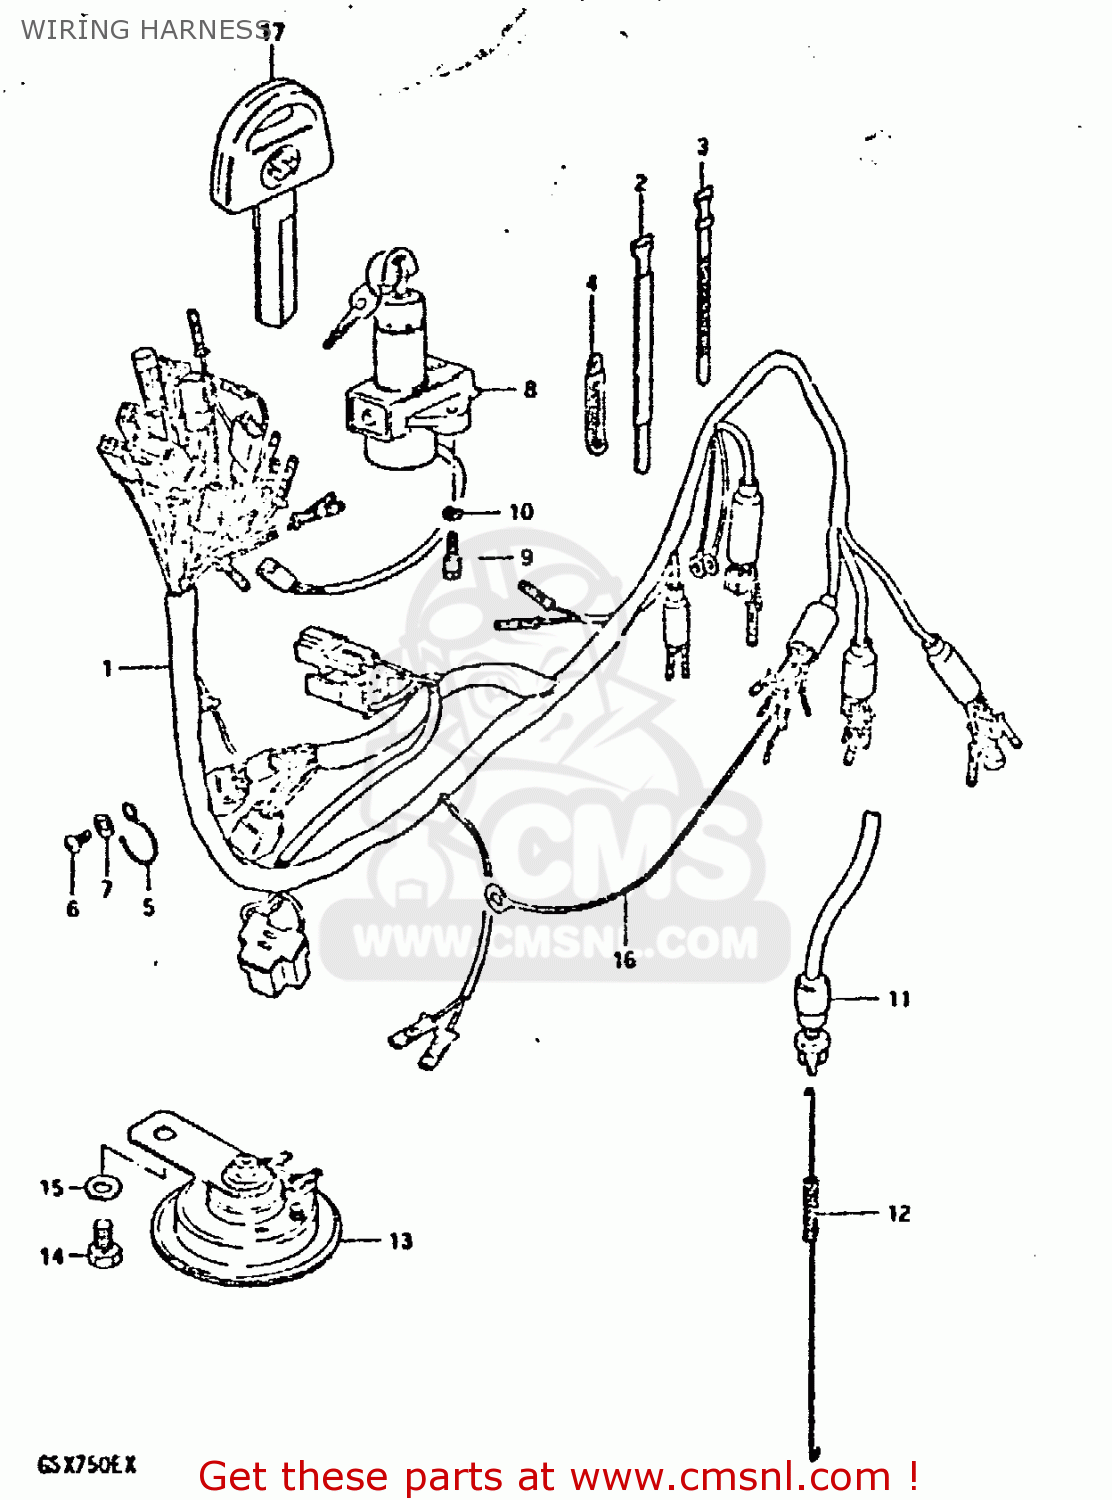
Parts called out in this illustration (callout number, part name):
1	HARNESS,WIRING
2	CLAMP
3	CLAMP(L:120)
4	CLAMP
5	GUIDE,WIRING HARNESS
6	SCREW 6X12
7	WASHER
8	LOCK ASSEMBLY,STEERING
9	BOLT
10	LOCK WASHER
11	SWITCH ASSEMBLY,STOP LAMP
12	SPRING
13	HORN ASSEMBLY,LOW PITCH
14	BOLT 8X12
15	WASHER
16	WIRE
17	KEY,BLANK
